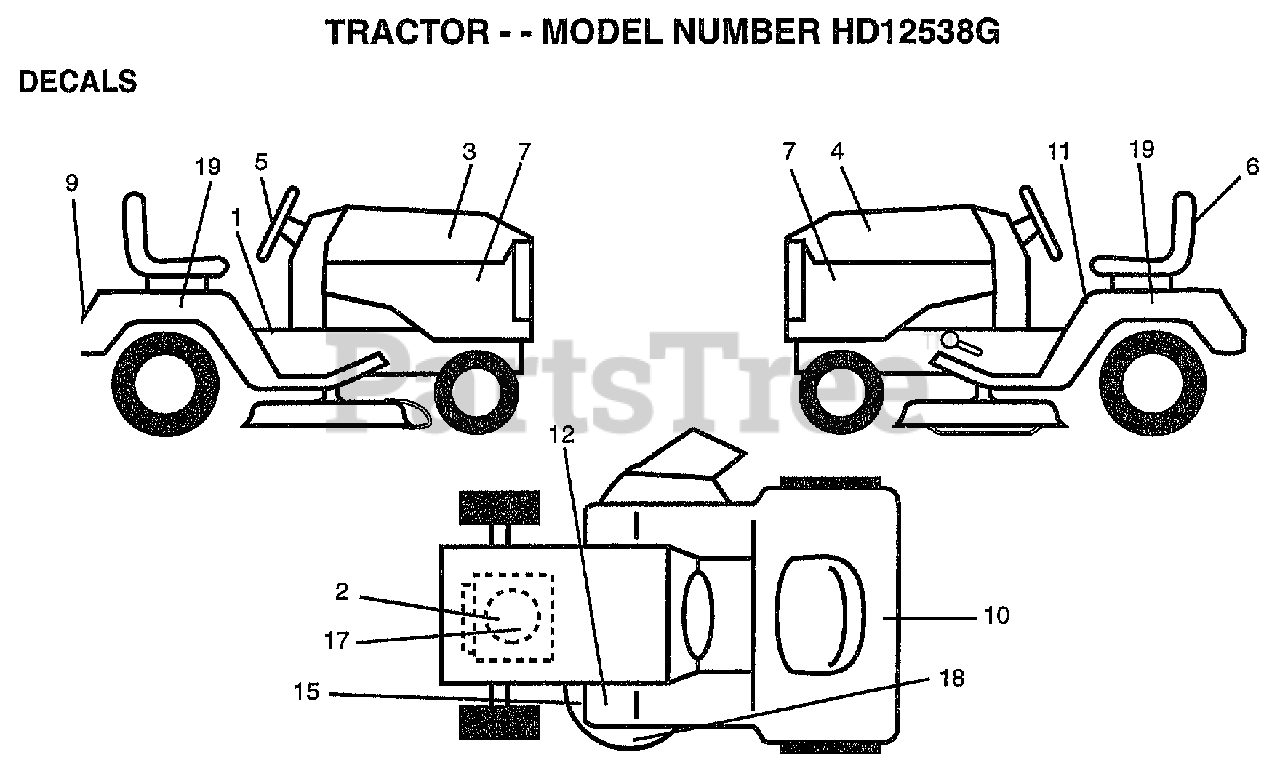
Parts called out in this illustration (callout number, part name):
3	DECAL.HOOD.RH.
4	DECAL.HOOD.LH
5	DECAL, INS STRG WH
6	DECAL.SEAT REPLACEMENT
7	DECAL.PANEL.SD.SP
9	DECAL.FENDER.LOGO
10	DECAL.BATRY.3-3908
11	"DECAL FENDER,DANG"
12	DECAL CLUT/BRAKE
15	DECAL
17	DECAL.ENGINE.REPL
18	DECAL.MOWER.HOME
19	DECAL.FEND.SD.5SP
